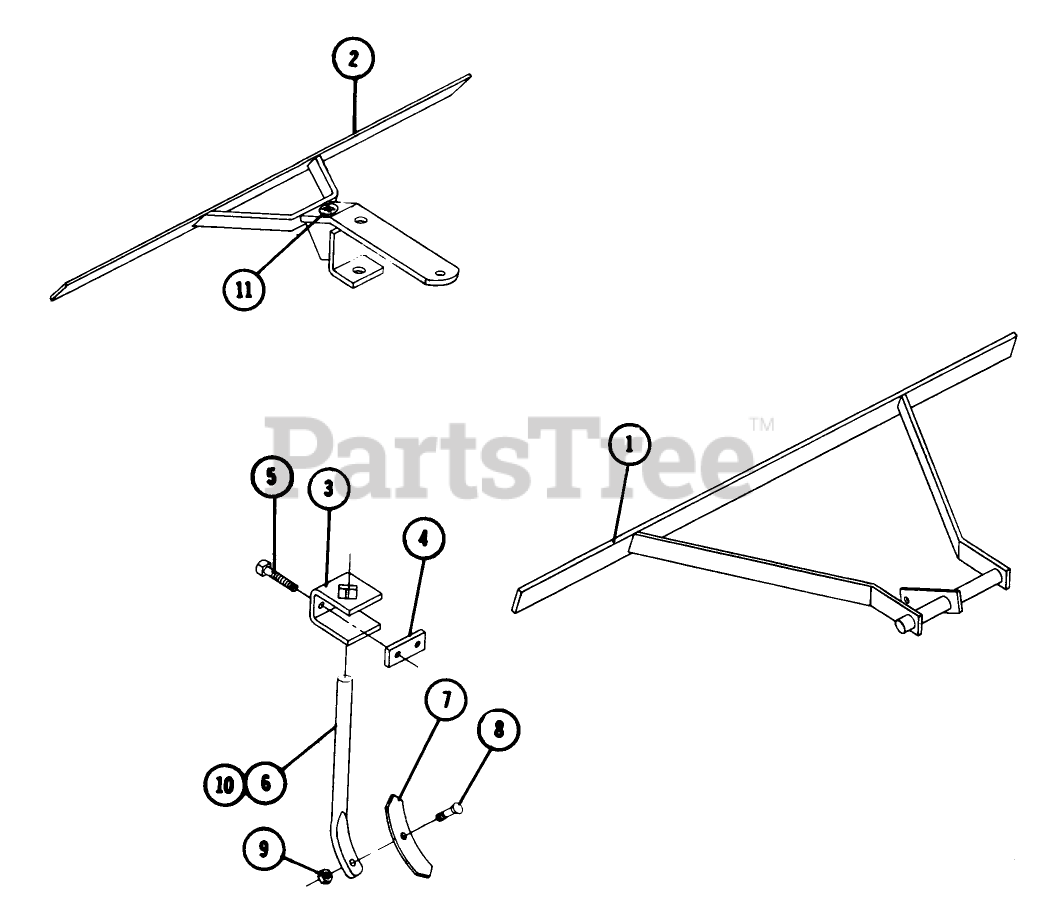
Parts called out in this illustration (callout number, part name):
1	Frame Assembly-Front
2	Frame Assembly-Rear
3	Clamp
4	PLATE
5	SQ HD CUP POINT SCR
6	Standard
7	Shovel
8	PLOW BOLT
9	Nut
10	STANDARD SHOVEL
11	DECAL-WHEEL HORSE
